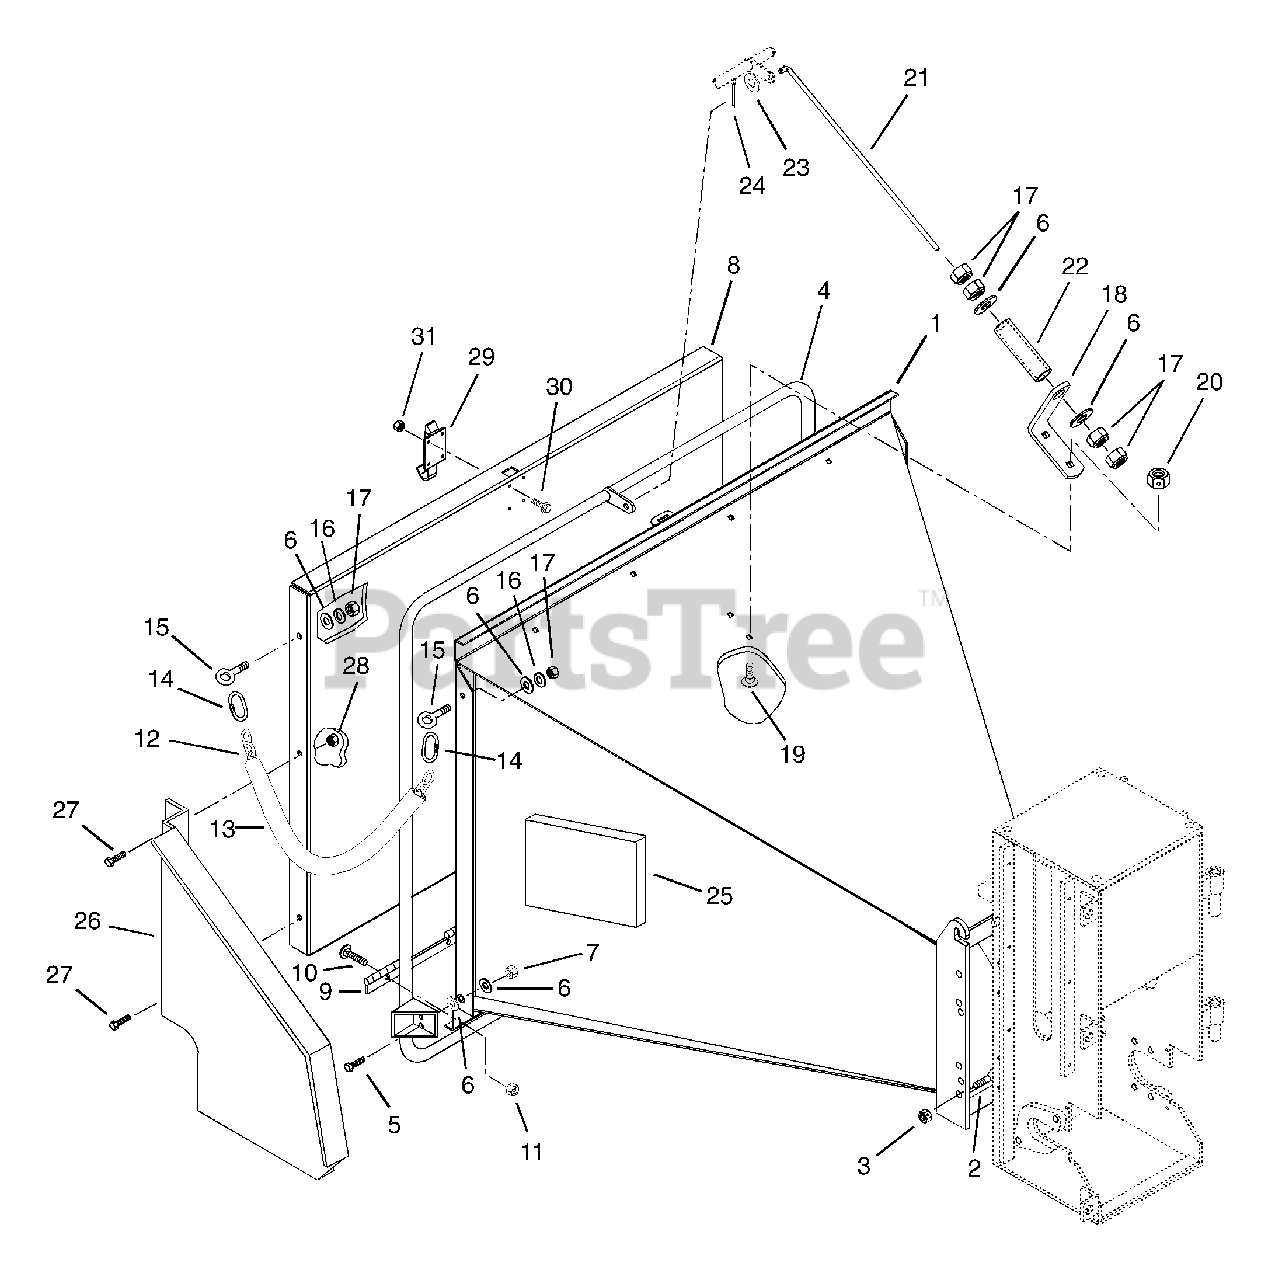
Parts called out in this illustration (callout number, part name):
1	Hopper Weldment
2	Screw-Machine-Flat-Countersunk .50-13 x 1.25
3	Nut-Locking-Center .50-13
4	Bar-Feed Control Weldment
5	Bolt-Hex .38-16 x 1.75 Grade 5
6	Washer-Flat-Steel .438 x 1.00 x .083
7	Nut-Locking-Center .38-16
8	Apron Weldment
10	Bolt-Round Head Square Neck .25-20 x .50 Grade 5
11	Nut-Locking-Center .25-20
12	Chain-1/4 inch x 28 Links Long
13	Tubing-Vinyl
14	Quick Link-Safety Type 5/16 inch
15	Bolt-Eye .375 x 1.250
16	Washer-Locking .38 x .094
17	Nut-Hex .38-16
18	Bracket-Valve Stop
19	Bolt-Round Head Square Neck .31-18 x .75 Grade 5
20	Nut-Locking-Center .31-18
21	Rod-Valve Stop
22	Tubing-Urethane .438 x .688
23	Washer-Flat-Steel .344 x .688 x .065
24	Pin-Cotter .12 x .75
25	Box-Literature
26	Side-Apron Right Hand
26	Side-Apron Left Hand
27	Bolt-Hex .38-16 x .50 Grade 5
28	Nut-Locking-Center .38-16
29	Latch
30	Screw-Machine 10-24 x .50
31	Nut-Locking-Nylon 10-24 w/Insert
